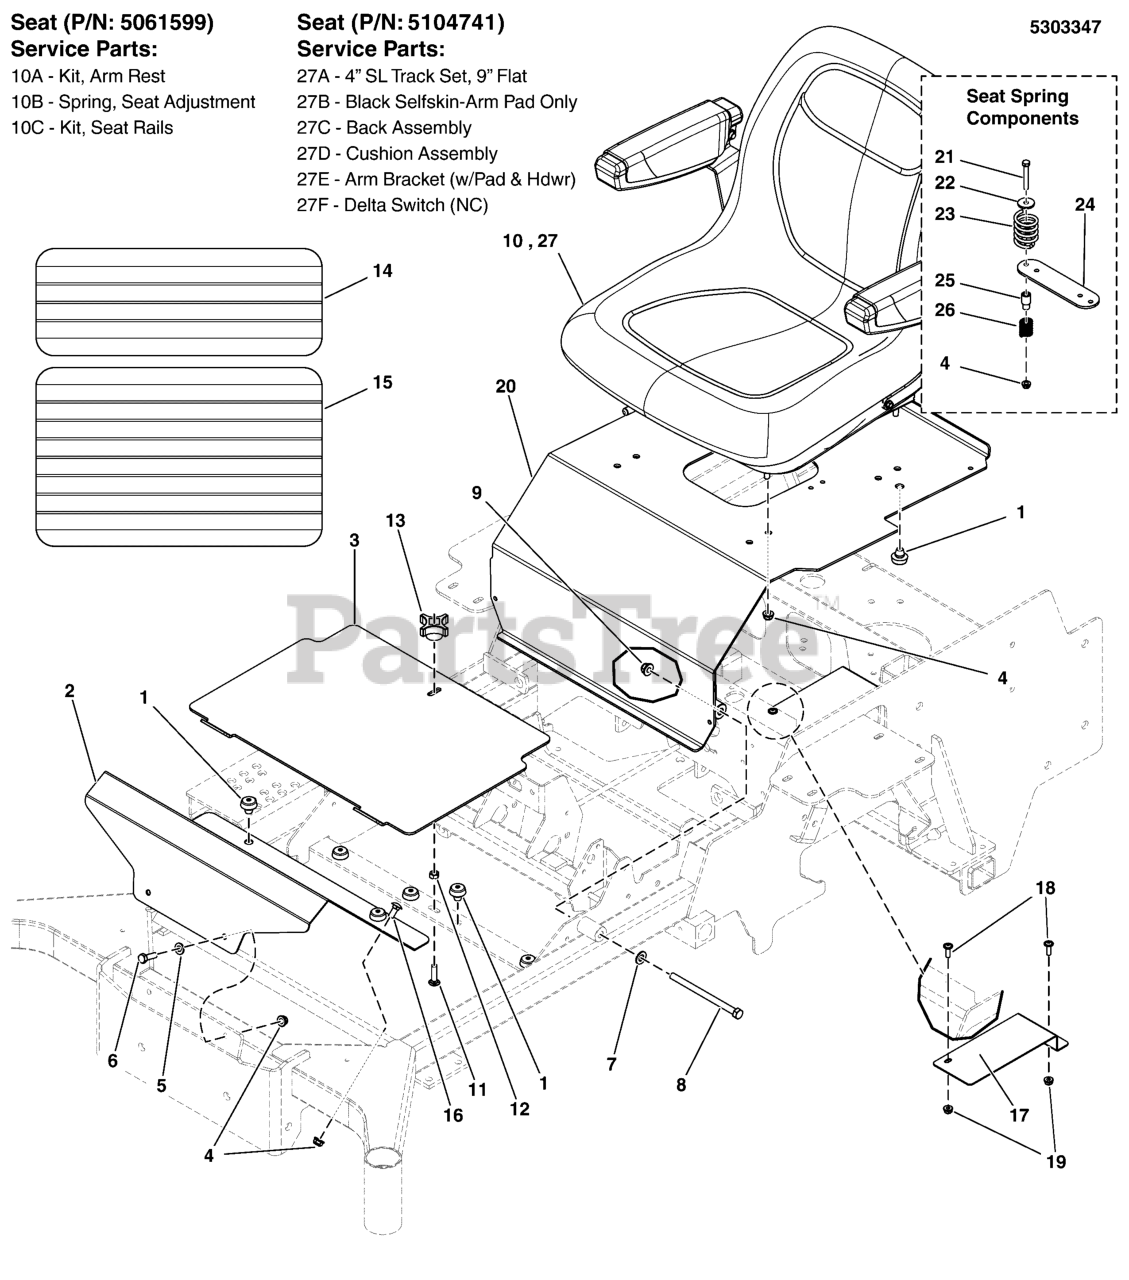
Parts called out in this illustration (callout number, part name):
1	MNT, VBRTN, RBBR
2	PLATE, FLOOR RIGID, S125XT - RED
3	PLATE, FLOOR, REMOVABLE, IS700 - RED
4	NUT, 5/16-18 HEX NYLOCK FLANGE
5	WASHER, 5/16" SAE
6	BOLT, 5/16-18 X 1 GD5 YZ
7	WASHER, 3/8 SAE
8	BOLT, 3/8-16 X 5-1/2" GD5 CZ
9	NUT, 3/8-16 HEX NYLOCK FLANGE
10	SEAT, XB-180, NO LOGO, BLACK
10A	ARMREST KIT
10B	SPRING, EXTENSION, SEAT ADJUSTMENT (BLK OR SLVR)
10C	SEAT RAIL, KIT, RH AND LH
11	BOLT, 5/16-18 X 1-1/4, CARRIAGE YZ
12	NUT, 5/16-18, HEX, CNTR LK, ZC/CL
13	KNOB-INT THR .312-18 4-ARM 2.12WD 1.06LG
14	SAFETY WALK, FLOOR REST, 6.00 X 16.00
15	SAFETY WALK, FLOOR PLATE, S50X, 10X16
16	BOLT, 5/16-18 X 3/4, CARRIAGE
17	PLATE, SEAT BELT GUARD - BLK
18	SCREW, 1/4-20 X 1, ALLEN BH, CZ
19	NUT, 1/4-20 HEX NYLOCK FLANGE
20	ASSM, SEAT PLATE W/ DECALS, F125XT
21	BOLT, 5/16-18 X 2-1/4 GD5 YZ
22	PLATE, SEAT SWITCH, RED
23	SPACER, .33 X .66 X 1.31 SHLDR, CZ
24	SPRING, COM 720ID X 1.31KG X .118WIRE
25	WASHER, .34 X 1.25 X 10GA
26	SPRING, SEAT SUPPORT
27	SEAT, 907 SEAT INC
27A	4" SL TRACK SET - 9" FLAT - W/HDWR
27B	ARM REST, BLACK MOLDED, PAD ONLY
27C	BACK ASSEMBLY FOR 907
27D	CUSHION ASSEMBLY FOR 907
27E	ARM BRACKET W/PAD & HARDWARE
27F	DELTA SWITCH - NORMALLY CLOSED
